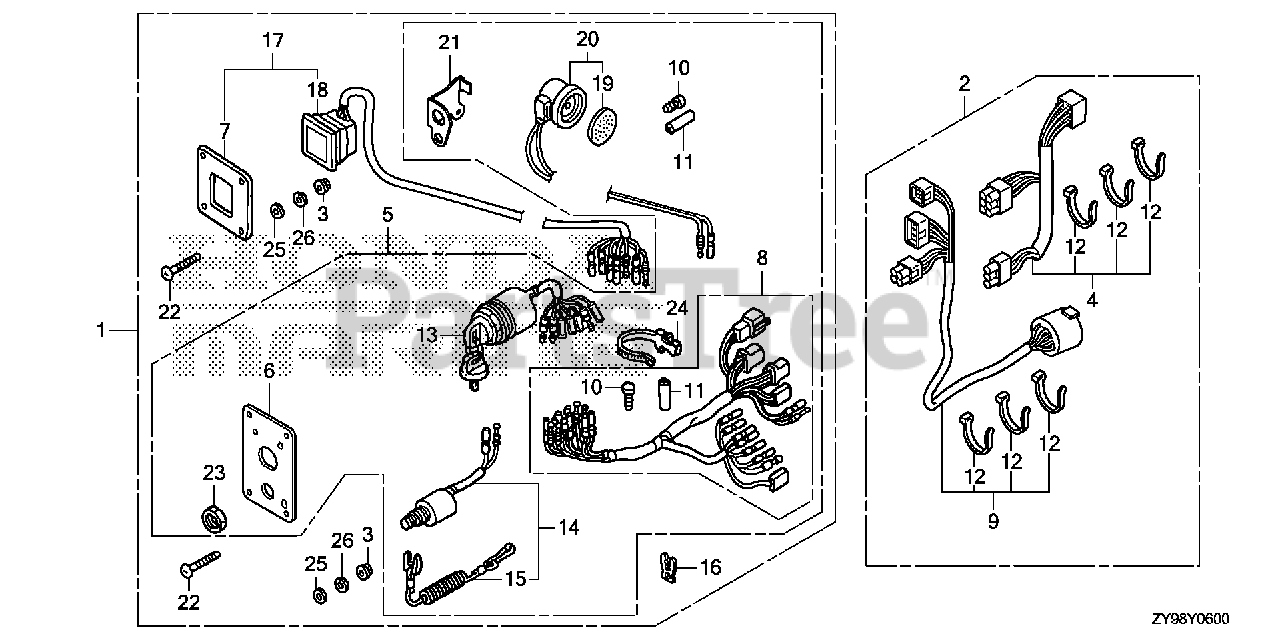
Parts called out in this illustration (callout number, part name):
1	PANEL KIT, SWITCH (4-LED) (B)
2	CABLE SET, PANEL INDICATOR (20FT)
2	CABLE SET, PANEL INDICATOR (25FT)
2	CABLE SET, PANEL INDICATOR (30FT)
3	NUT, FLANGE (5MM)
4	WIRE ASSY., INDICATOR (20FT)
4	WIRE ASSY., INDICATOR (25FT)
4	WIRE ASSY., INDICATOR (30FT)
5	PANEL ASSY., SWITCH
6	PANEL, CONTROL
7	PANEL, CONTROL
8	HARNESS ASSY., SWITCH PANEL
9	CABLE ASSY., SWITCH PANEL (20FT) (NHK MEC)
9	CABLE ASSY., SWITCH PANEL (25FT) (NHK MEC)
9	CABLE ASSY., SWITCH PANEL (30FT) (NHK MEC)
10	PLUG, CONNECTOR (INNER)
11	PLUG, CONNECTOR (OUTER)
12	TIE, CABLE (2.4X92) (NATURAL)
13	SWITCH ASSY., COMBINATION
14	SWITCH ASSY., EMERGENCY STOP
15	WIRE, EMERGENCY
16	CLIP, EMERGENCY LOCK
17	PANEL ASSY., INDICATOR (4-LED)
18	LAMP ASSY., INDICATION (4-LED)
19	PLATE, TURN SIGNAL BUZZER
20	BUZZER, WARNING
21	BRACKET, BUZZER
22	SCREW, PAN (5X40)
23	NUT, HEX. (16MM)
24	BAND, WIRE HARNESS (150MM) (NATURAL)
25	WASHER, PLAIN (5MM)
26	WASHER, SPRING (5MM)
